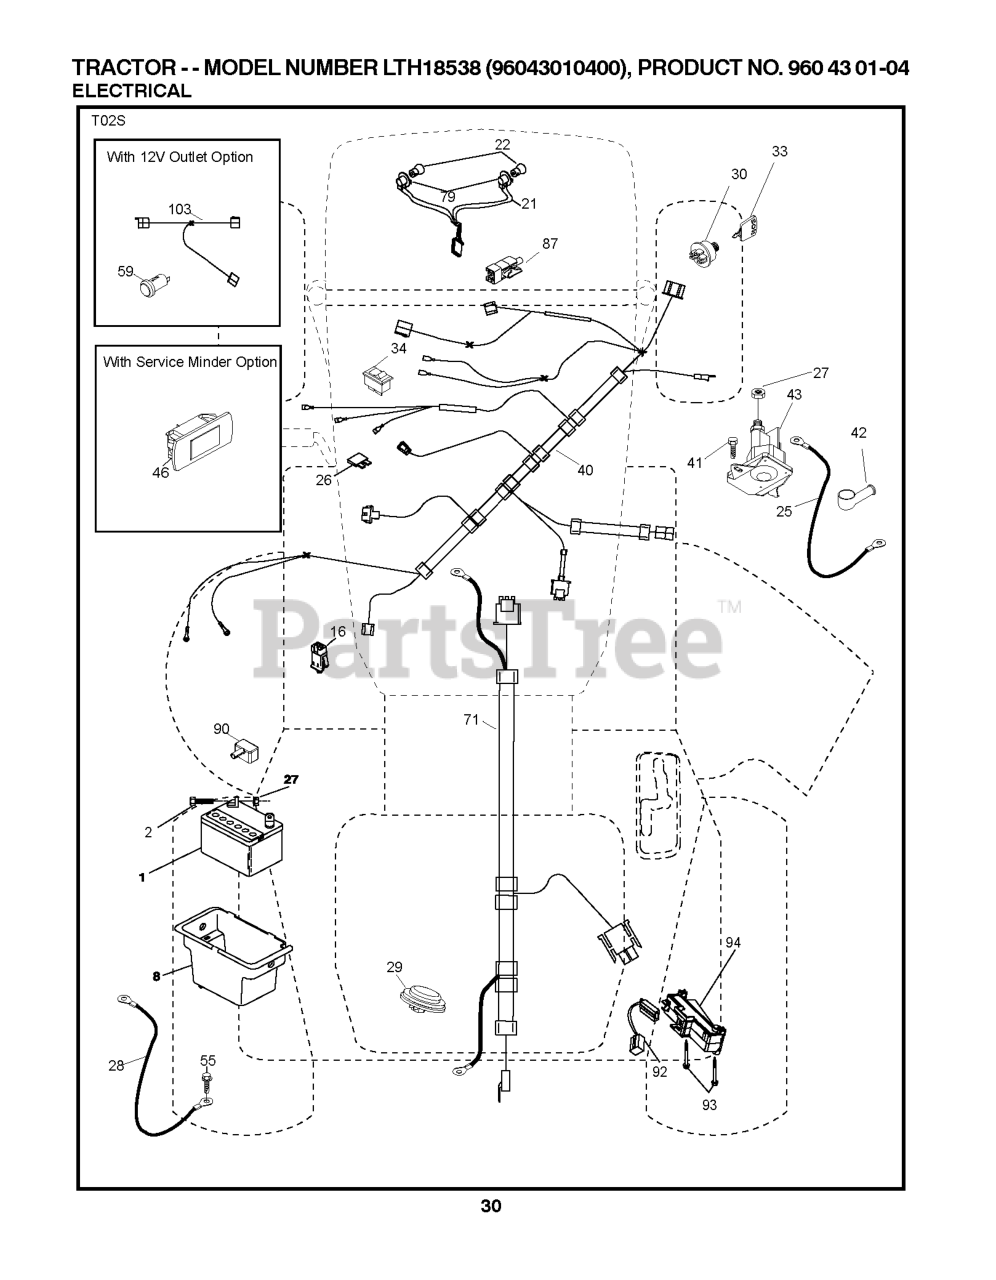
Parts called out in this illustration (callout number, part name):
1	Battery 12 Volt 25 Amp
2	BOLT.HEX.1/4.X.3/4.DICHROMATE
8	BOX.BATTERY.MNT.REAR.L
16	SWITCH INTERLOOK PUSH-IN
21	HARNESS.LIGHT W/4152J BULBS
25	CABLE.STARTER.6GA.BL/RED.14.
26	FUSE 20AMP
27	NUT
28	CABLE.BLACK.18"REAR.BA
29	SWITCH.SEAT.DELTA.OPC.
30	SWITCH.IGN.DELTA.W.LGH.ROS
33	KEY.CHAIN.BLISTER.PACK.GEN.INT
40	HARNESS IGN. DASH
41	SCREW
42	TERMINAL COVER
43	SOLENOID.W/BRASS.PLUNGER
55	SCREW 5/16"
71	HARNESS.IGN.CHASS.TEX.REAR.BAT
79	BULB HOLDER ASM.
87	SWITCH.INTRLCK.CLUTCH.
90	COVER, TERMINAL BATTERY
92	HARNESS.PIGTAIL.CONSLE
93	SCREW.PLASTITE
94	MODULE.REVERSE.ROS
